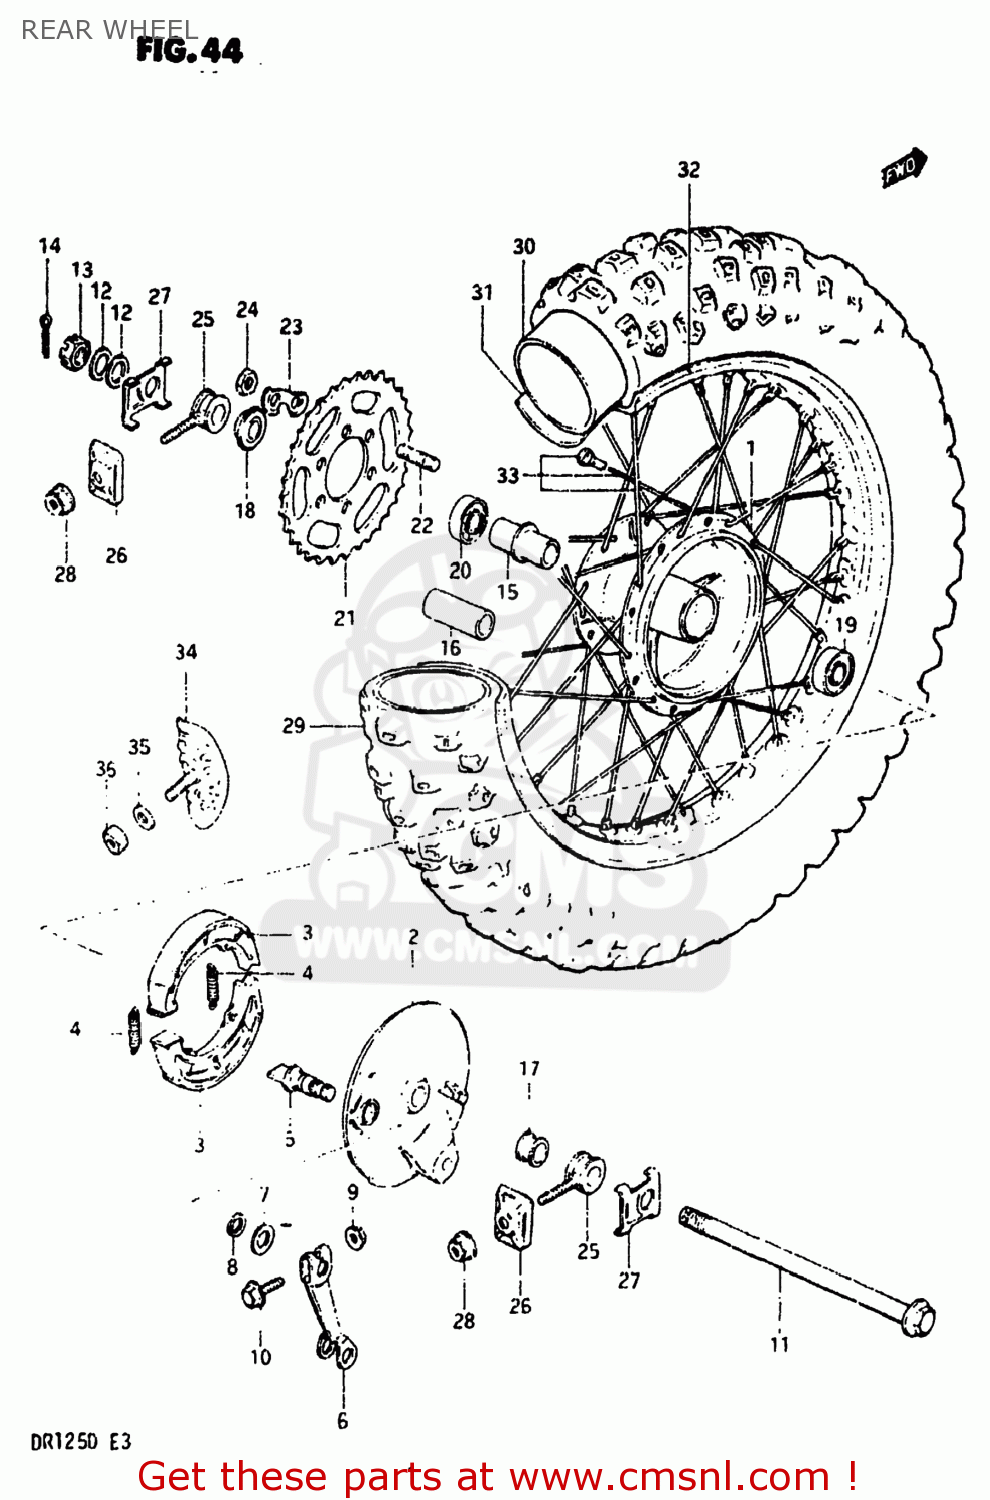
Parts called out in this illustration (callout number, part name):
1	HUB,REAR WHEEL
2	PANEL,RR BRAKE ANCHOR
3	SHOE,BRAKE
4	SPRING(L:34)
5	CAM,FRONT BRAKE
6	LEVER,RR BRAKE CAM
7	WASHER (14.5X22X1.6)
8	O-RING (D:2.4 ID:13.8)
9	NUT
10	BOLT
11	AXLE,REAR
12	WASHER
13	NUT
14	COTTER PIN
15	SPACER,RR WHEEL HUB BEARING
16	SPACER(15.3X21.7X107.5)
17	SPACER,RR AXLE,R
18	SPACER,REAR AXLE,LEFT
19	BEARING
20	BEARING
21	SPROCKET,RR(NT:47)
22	BOLT,STUD
23	WASHER
24	NUT
25	ADJUSTER,CHAIN
26	PLATE,CHAIN ADJUSTER
27	WASHER,CHAIN ADJUSTER GUIDE
28	NUT
29	TIRE
30	TUBE 3.50-17 089-432MM
31	PROTECTOR,WHEEL,INNER
32	RIM,REAR WHEEL
33	SPOKE SET,REAR
34	STOPPER,BEAD
35	WASHER
36	NUT
